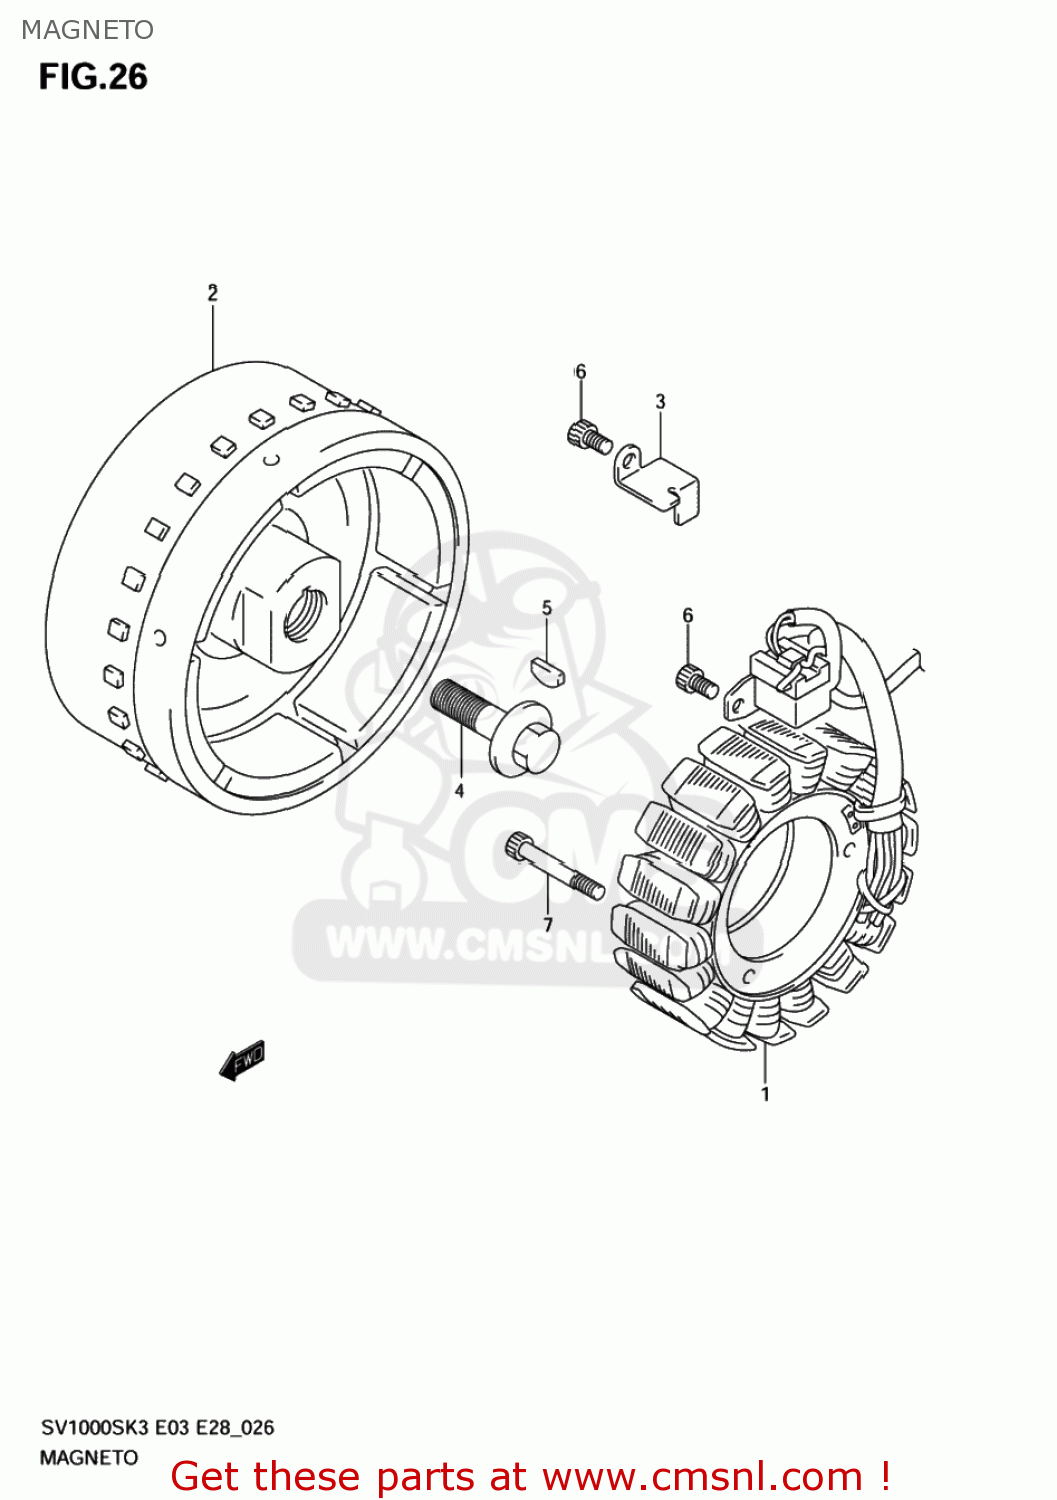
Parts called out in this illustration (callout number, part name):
1	STATOR ASSY
2	ROTOR ASSY
3	CLAMP,MAGNETO LEAD NO.1
4	BOLT,MAGNETO ROTOR
5	KEY
6	BOLT
7	BOLT
